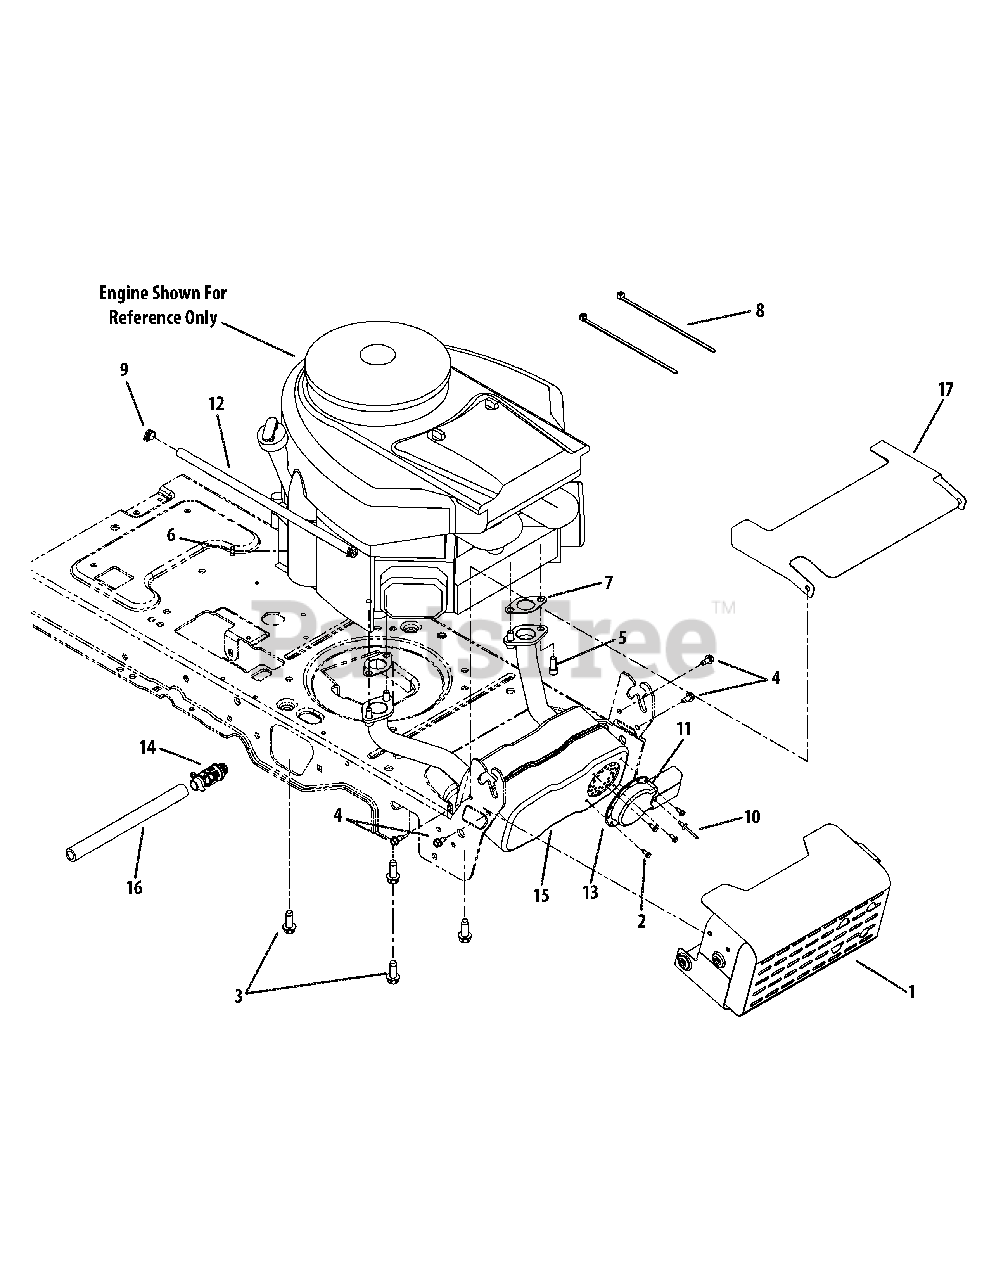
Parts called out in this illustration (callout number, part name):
1	Muffler Shield Assembly
2	Hex Washer Screw, #8-18 x .500
3	Hex Washer Screw, 3/8-16 x 1.000
4	Hex Washer Screw, 1/4-20 x .500
5	Screw, 5/16-18 x .750
6	Sems Nut, 1/4-20
7	Exhaust Gasket
8	Cable Tie, 3/16 x .05 x 7.4
9	Hose Clamp
10	Rivet, .188 x .300
11	Muffler Deflector
13	Long Muffler Deflector
15	Muffler
16	Oil Drain Extension Hose
17	Heat Shield
